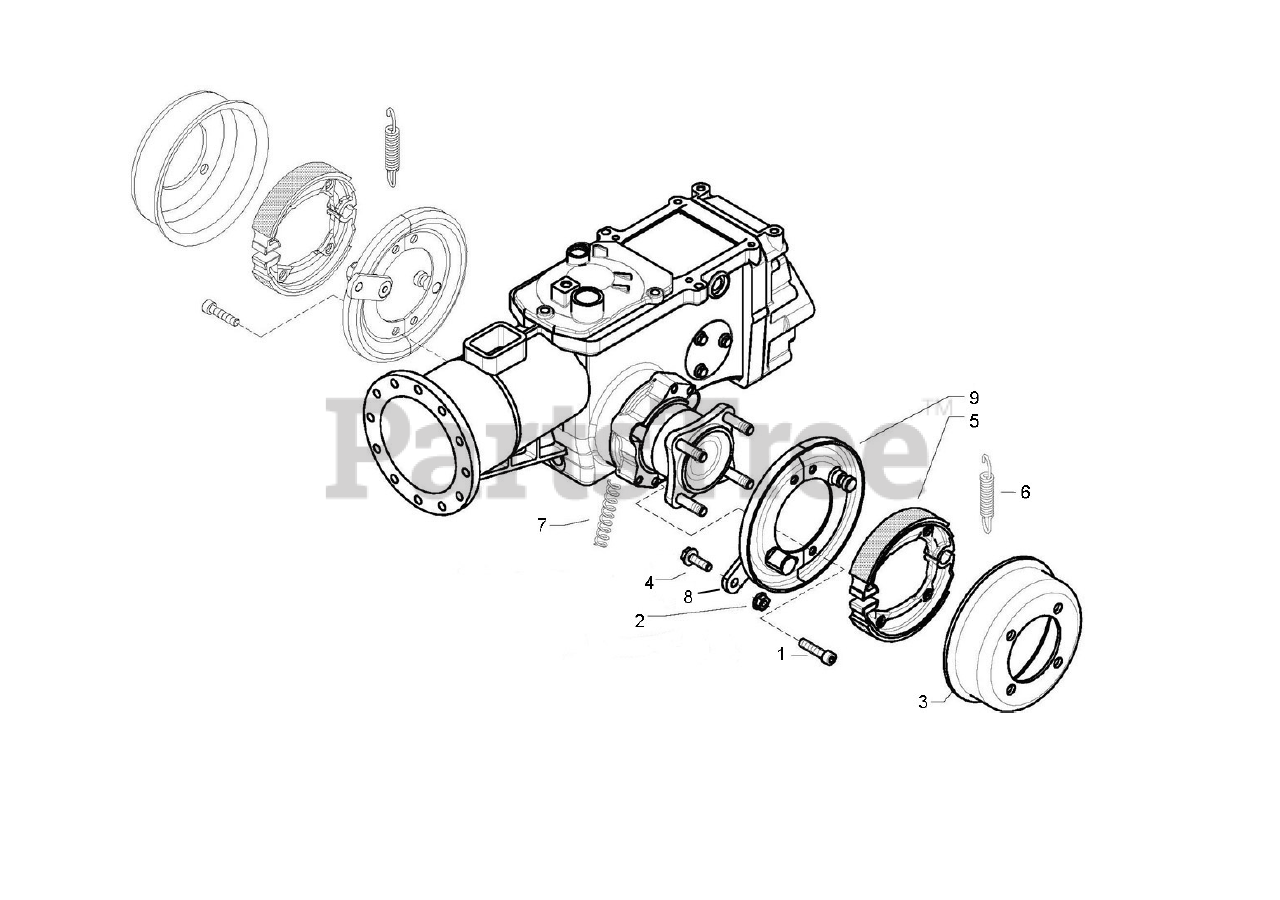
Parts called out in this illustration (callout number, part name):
1	SCREW TCEI M8X25 UNI 5931
2	SELFLOCK NUT M8 6S DIN 6927
3	BRAKE DRUM
4	STOP
5	BRAKE BLOCK
6	SPRING
7	SPRING
8	LEVER, HALF DISC COMPLETE
9	PIN, HALF DISC COMPLETE
